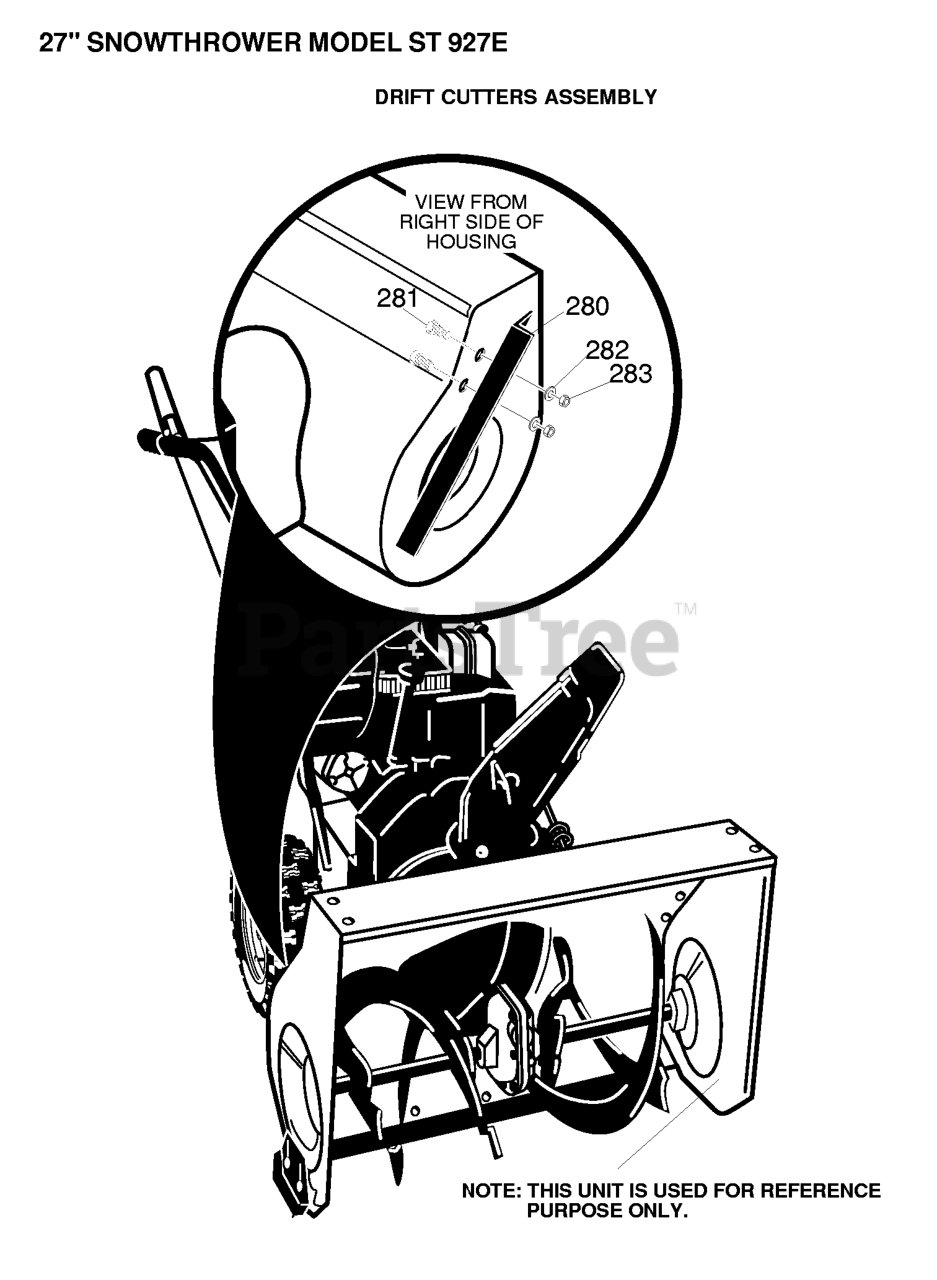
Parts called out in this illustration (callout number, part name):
280	BAR, DRIFT CUTTER
282	WASHER, HVSPTLK .328X.60X
283	NUT, 5/16-18 REGHEX
